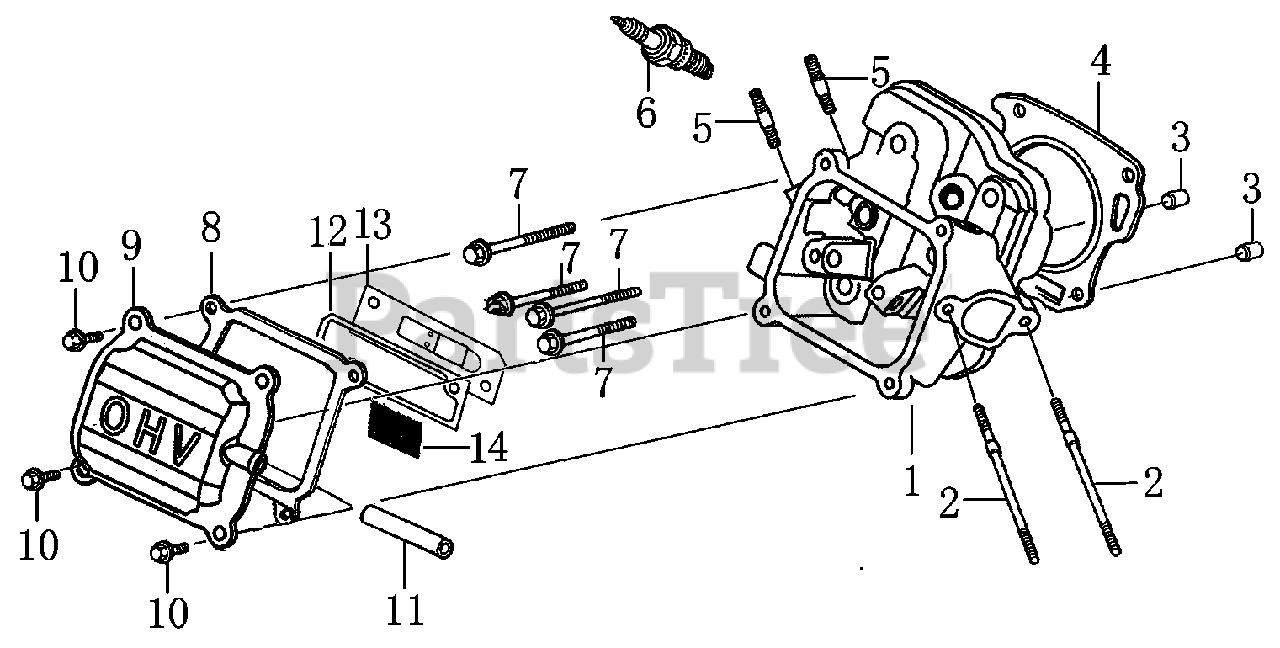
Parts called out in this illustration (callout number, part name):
1	HEAD, CYLINDER
2	BOLT, STUD, INTAKE
3	PIN, DOWEL
4	GASKET, CYLINDER HEAD
5	BOLT, STUD , EXHAUST
6	PLUG, SPARK
7	BOLT, FLANGE HEAD 8*60
8	GASKET, VALVE COVER
9	COVER, VALVE
10	BOLT, FLANGE , 6*14
11	TUBE, BREATHER
12	GASKET BREATHER CHAMBER
13	CAP, BREATHER CHAMBER
14	OIL STRAINER
